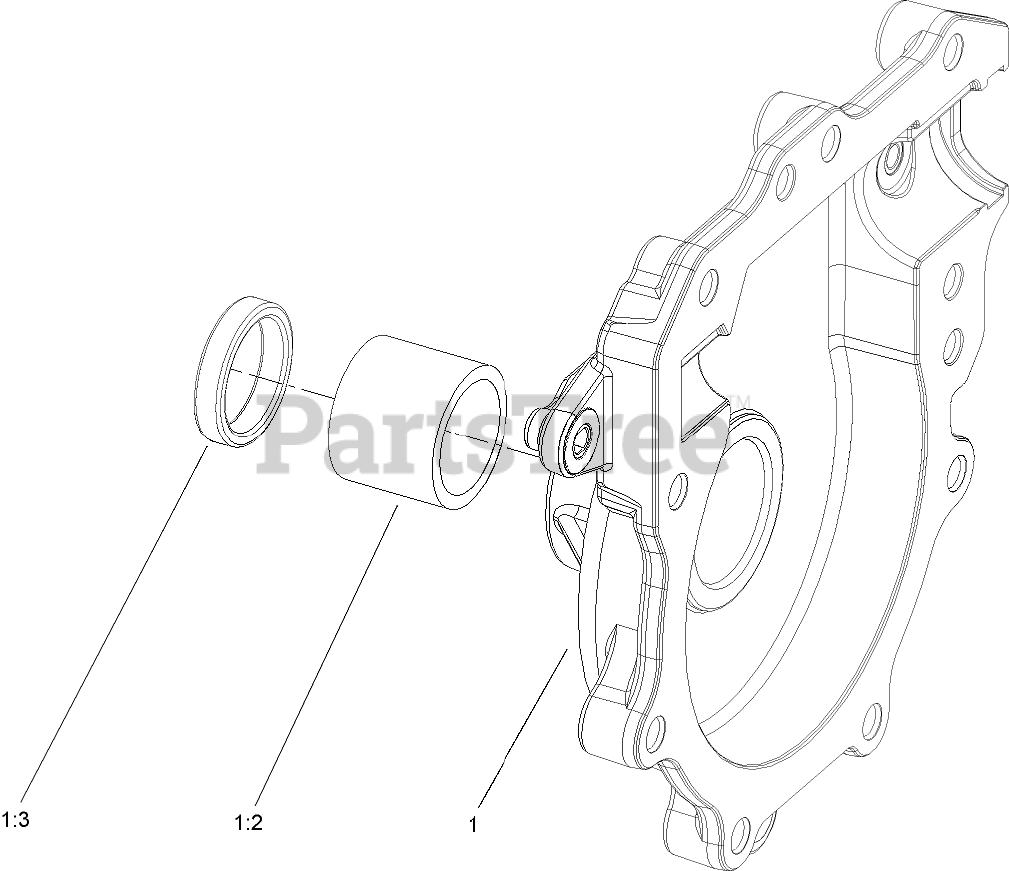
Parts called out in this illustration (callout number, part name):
1	R.H. AUGER GEARCASE ASM
1:2	BUSHING
1:3	SEAL-OIL
